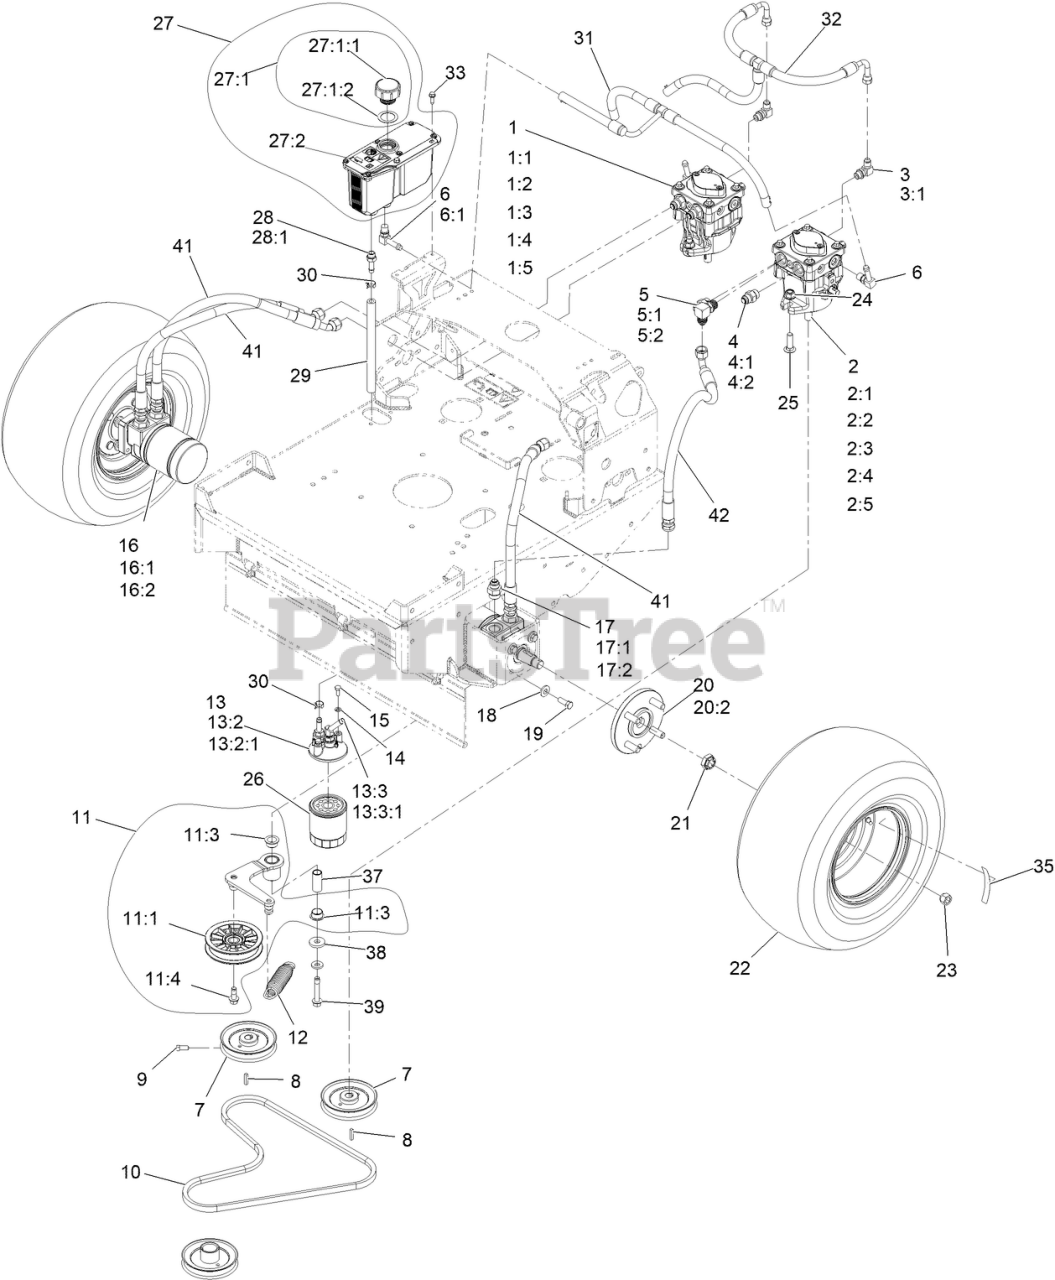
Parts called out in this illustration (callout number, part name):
1	PUMP-HYD PE RH TTH
1:1	INPUT SHAFT KIT
1:2	BEARING-THRUST
1:3	CYLINDER BLOCK KIT
1:4	SEAL OVERHAUL KIT
1:5	KIT, 10CC/12CC PUMP KIT
2	PUMP-HYD PE LH TTH
2:1	INPUT SHAFT KIT
2:2	BEARING-THRUST
2:3	CYLINDER BLOCK KIT
2:4	SEAL OVERHAUL KIT
2:5	KIT, 10CC/12CC PUMP KIT
3	FITTING-ELBOW, 90 DEG
3:1	O-RING
4	FITTING-STRAIGHT
5	FITTING-90 DEG
6	FITTING-ELBOW, 90
6:1	O-RING
7	SHEAVE ASM
9	SCREW-SET, SQH
10	BELT
11	ASM, PUMP IDLER
11:1	PULLEY-IDLER, FLAT
11:3	BUSHING-FLANGE
11:4	SCREW-HFH
12	SPRING-EXTENSION
13	ASM, FILTER HEAD
13:2	ADAPTER-STRAIGHT
13:2:1	O-RING
13:3	FITTING-BARBED, 45 DEG
13:3:1	O-RING
14	WASHER-LOCK
15	SCREW-HH
16	HYD MOTOR ASM
16:1	SEAL KIT
16:2	BEARING AND SEAL KIT
17	FITTING-STRAIGHT
17:1	O-RING
18	WASHER-BELLEVILLE
19	SCREW-HH
20	WHEEL HUB ASM
20:2	STUD-WHEEL
21	NUT-LOCK
22	ASM, DRIVE TIRE
23	NUT-LUG
24	NUT-HF, NI
25	BOLT-CARR
26	FILTER-25 MICRON, BI-DIRECTIONAL
27:1	Reservoir-HYD
27:1:1	Cap-Reservoir, HYD
27:1:2	GASKET-CAP
27:2	DECAL-WARNING
28	ADAPTER-STRAIGHT
28:1	O-RING
29	HOSE-CHARGE
30	CLAMP-HOSE
31	HOSE, CASE
32	HOSE, CHARGE
33	SCREW-HWH, THREAD ROLL
35	DECAL-TORQUE WHEEL LUG-HU
37	PIVOT, IDLER
39	SCREW-HHF
41	HOSE,HYDRAULIC W/COVER
42	HYD HOSE ASM
